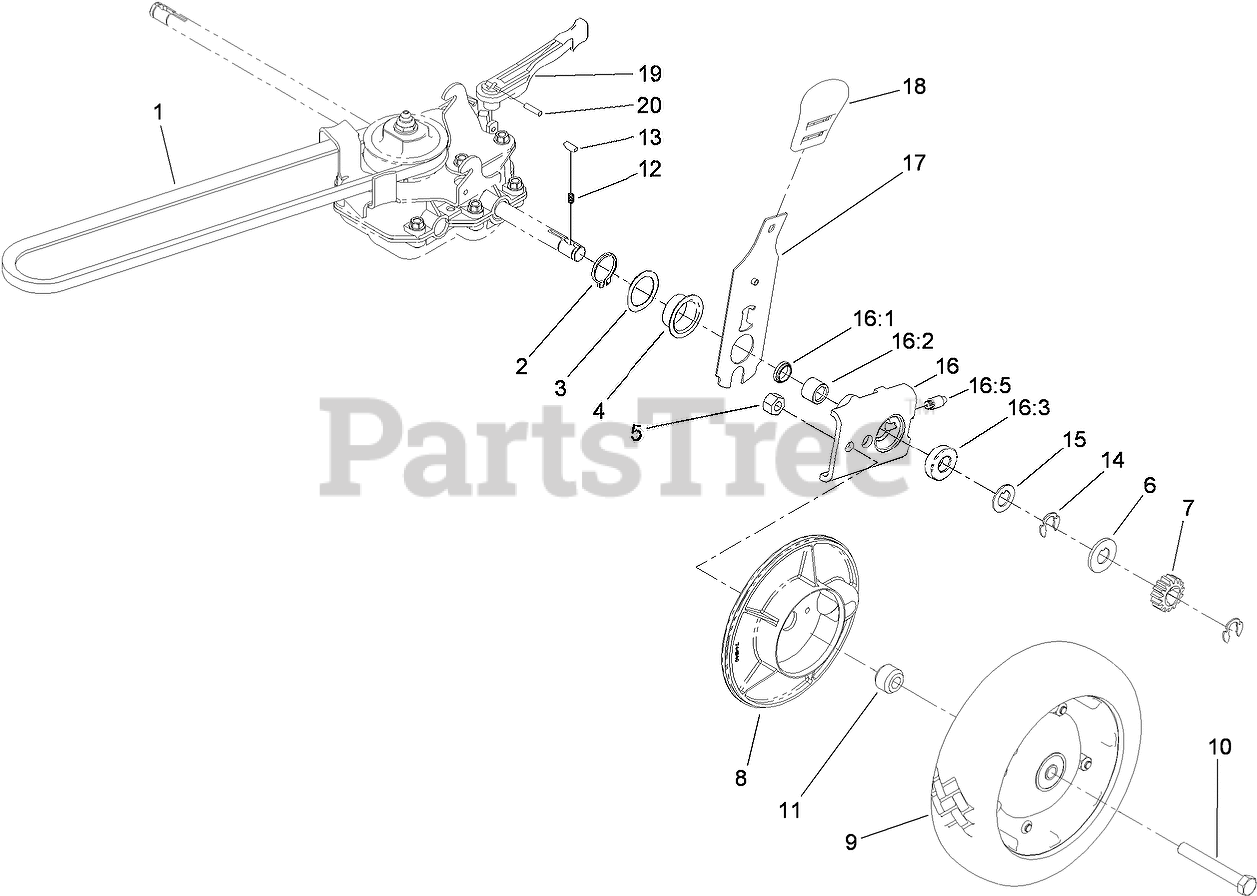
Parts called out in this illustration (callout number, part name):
1	V-BELT
2	RING-RETAINING
3	WASHER
4	CAP-END
5	NUT-LOCK, CONE
6	WASHER-THRUST, OUTER
7	GEAR-PINION
8	COVER-WHEEL
9	Wheel And Tire ASM
10	SCREW-HH
11	SPACER-COVER, WHEEL
12	SPRING-COMPRESSION
14	RING-RETAINING
15	WASHER-THRUST, OUTER
16	PIVOT ARM ASM
16:1	SEAL-OIL
16:2	BEARING-CAGED NEEDLE ROLLER
16:3	BEARING-WHEEL
17	REAR SPRING ARM ASM
18	KNOB-HOC
19	LEVER-SHIFT
20	PIN-COIL
